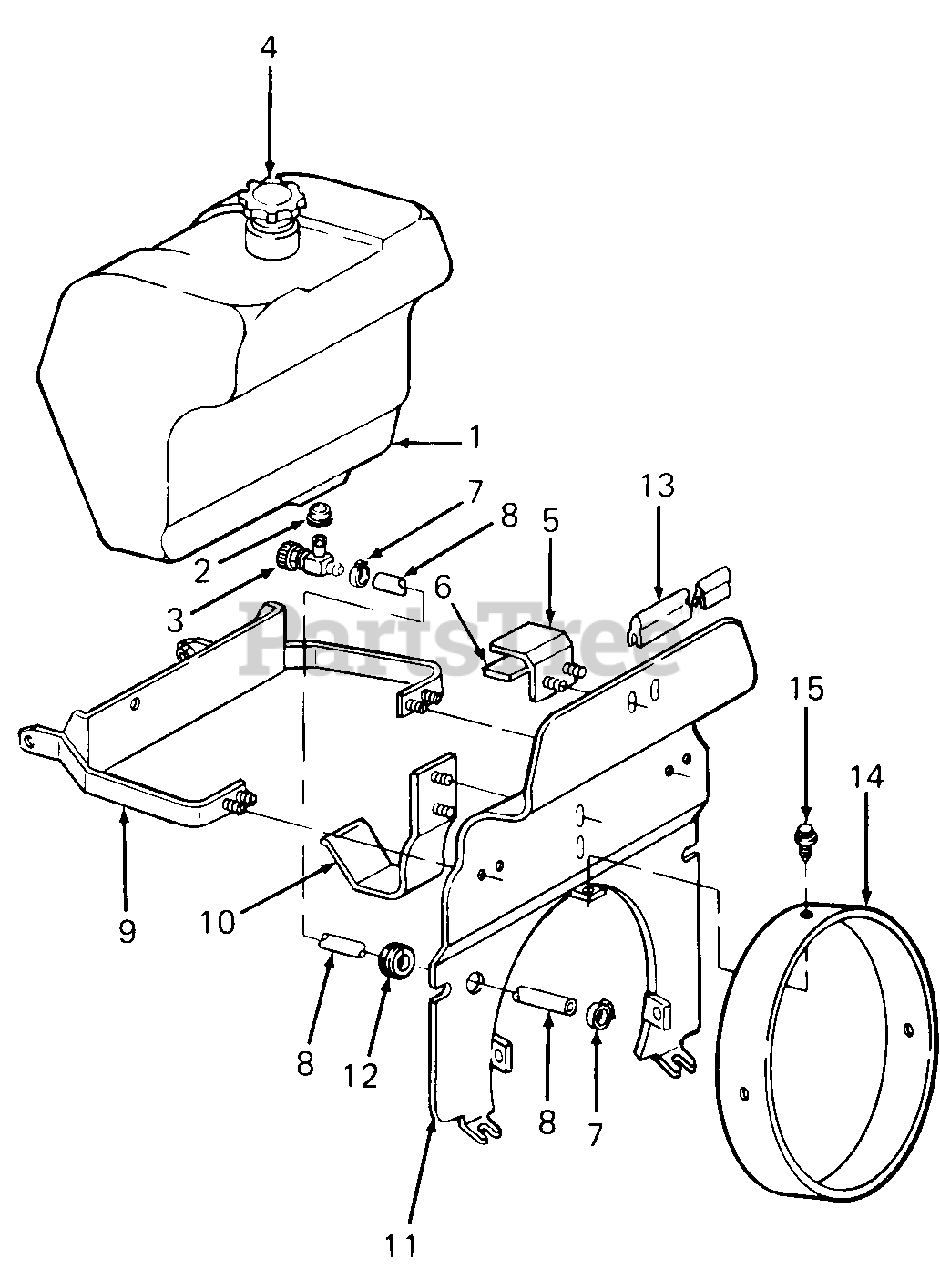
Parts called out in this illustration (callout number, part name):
1	Tank, Fuel
2	Bushing
3	Valve, Shutoff w/Screen
4	Gauge, Fuel Cap
5	Clamp, Fuel Tank
6	Pad, Fuel Tank Adhesive, Loctite #495
7	Clamp, Hose
8	Line, Fuel -14 in. Lg
9	Support, Fuel Tank
10	Support, Fuel Tank Bottom
11	Deflector, Heat
13	Seal, Heat Baffle, 56 in Lg
14	Shroud, Blower
15	Screw, Hex Wash Hd AB Tapp, #10 X .50 Lg
